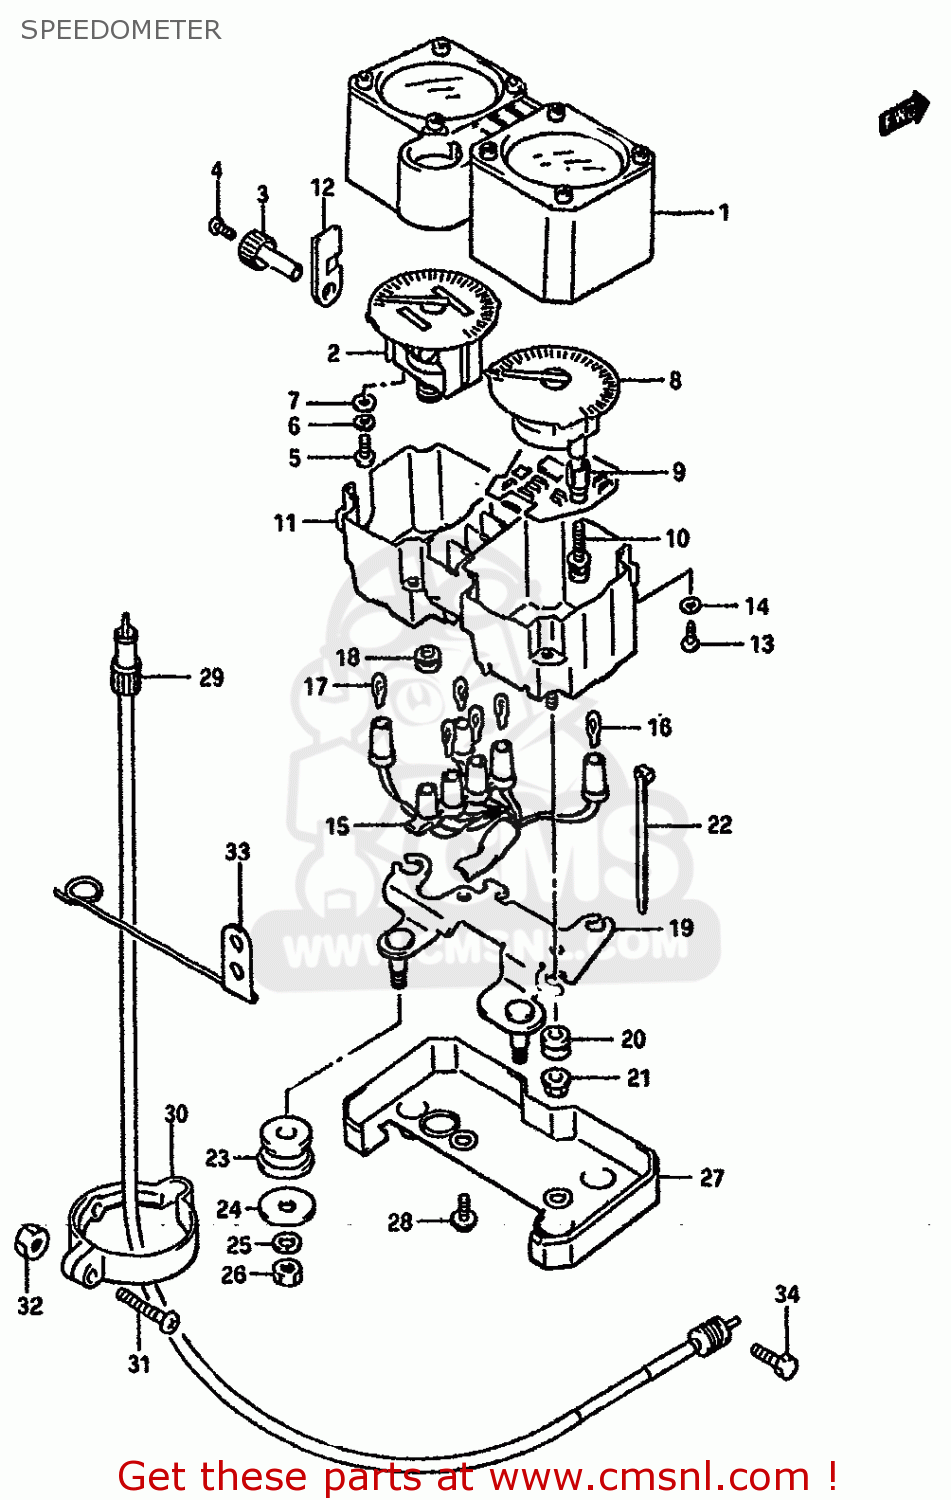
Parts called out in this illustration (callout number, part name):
1	HOOD,METER
2	SPEEDOMETER
3	KNOB,TRIP
4	SCREW,TRIP KNOB
5	SCREW
6	LOCK WASHER
7	WASHER 3.3X8X0
8	TACHOMETER
9	SPACER
10	SCREW
11	CASE,METER
12	CUSHION,METER
13	SCREW
14	LOCK WASHER
15	SOCKET,METER
16	BULB(12V3W,WB371,T7)
17	BULB(12V1.7W,WB372,T7)
18	CAP
19	BRACKET,METER
20	CUSHION,METER
21	NUT
22	CLAMP
23	CUSHION,METER BRACKET
24	WASHER (8.5X20X1.6)
25	WASHER,LOCK,8.
26	NUT
27	COVER,LOWER
28	SCREW
29	CABLE ASSY
30	CLAMP,CABLE
31	SCREW
32	NUT
33	GUIDE, SPEEDOMETER CABLE
34	BOLT
